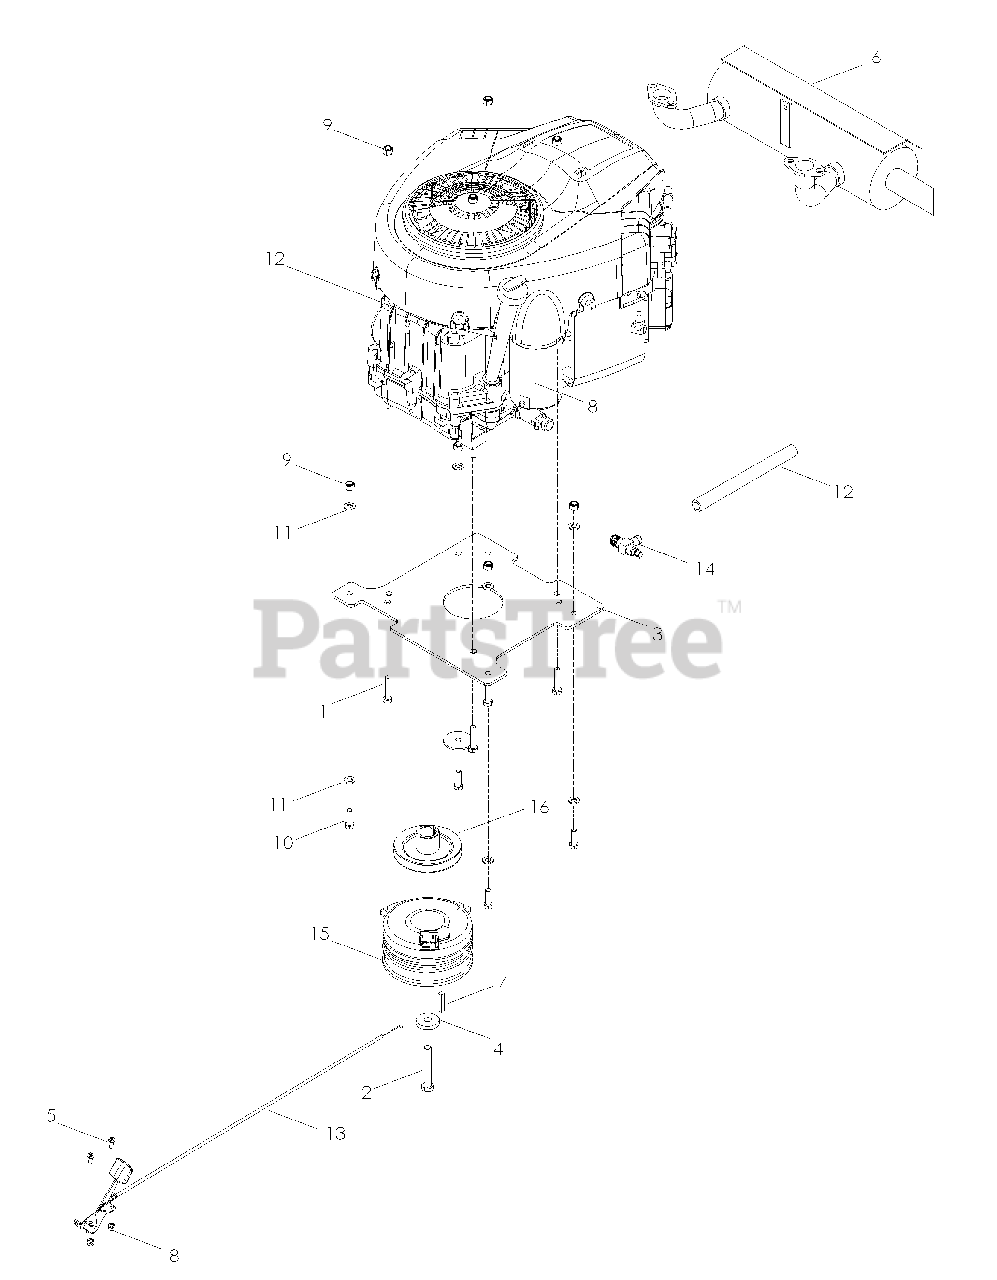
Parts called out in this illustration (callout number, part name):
1	CAPSCREW 5/16 X 1/1/2 HEX HEAD
2	HCS 7/16-20 X 2-3/4
3	PLATE, ENGINE MOUNT BLUE
4	WASHER .43X1.38X.25
5	SCREW #10-24 X 5/8
6	MUFFLER
7	KEY 1/4`SQ X 1-1/4`
8	NUT 10-24 NYLOC
9	NUT 5/16 NYLOC
10	HCS 5/16C X 1
11	FLAT WASHER 5/16 SAE
12	OIL DRAIN HOSE
13	CABLE THROTTLE
14	OIL DRAIN
15	ELEC. CLUTCH
16	ENGINE PULLEY
